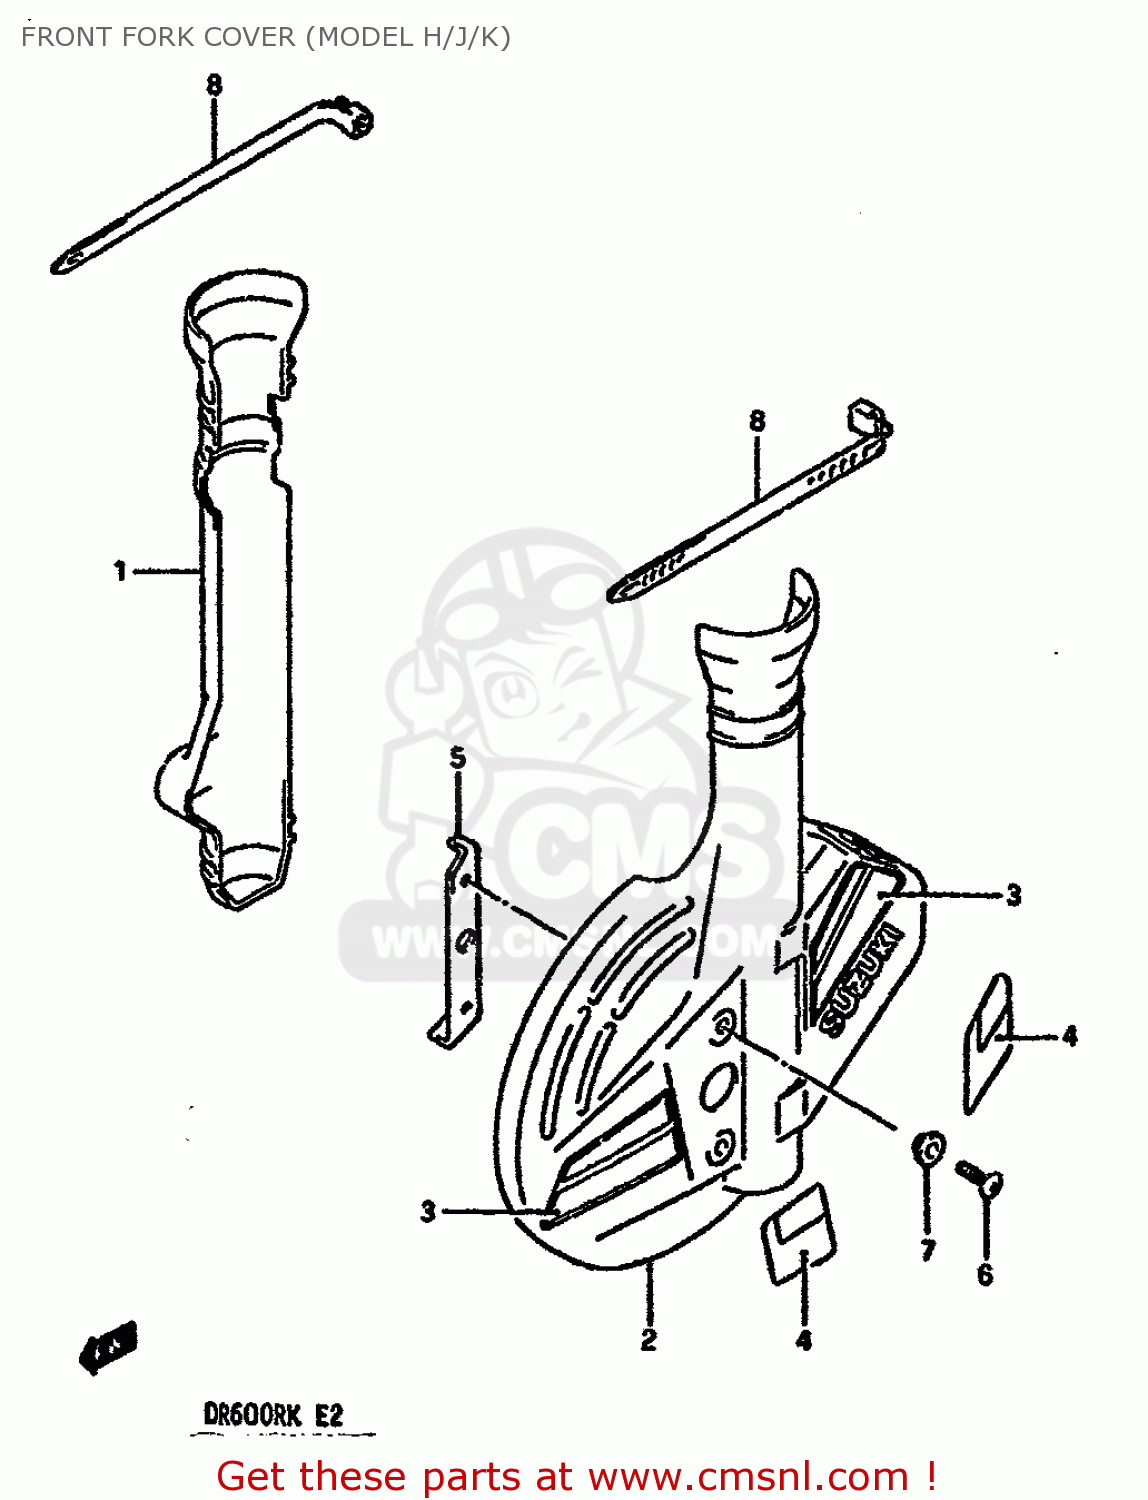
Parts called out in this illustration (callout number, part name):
1	PROTECTOR,FR FORK,R
2	PROTECTOR, FRONT FORK LH
3	TAPE SET,DISC PROTECTOR
4	TAPE SET,DISC COVER BRAKE
5	PLATE, PROTECTOR SET
6	SCREW 6X12
7	WASHER
8	CLAMP
